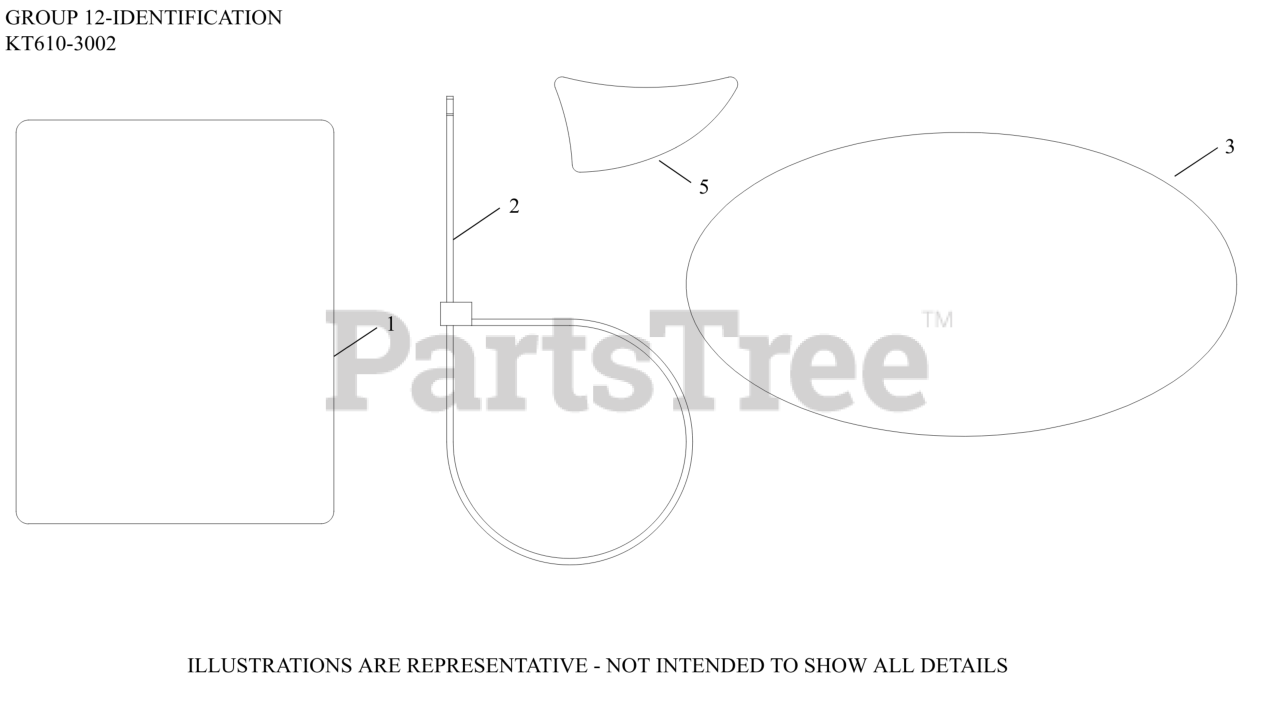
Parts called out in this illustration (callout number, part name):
1	LABEL, CLEAR LAMINATION
3	LABEL, 6000 SERIES (19HP)
5	LABEL, SMART CHOKE
